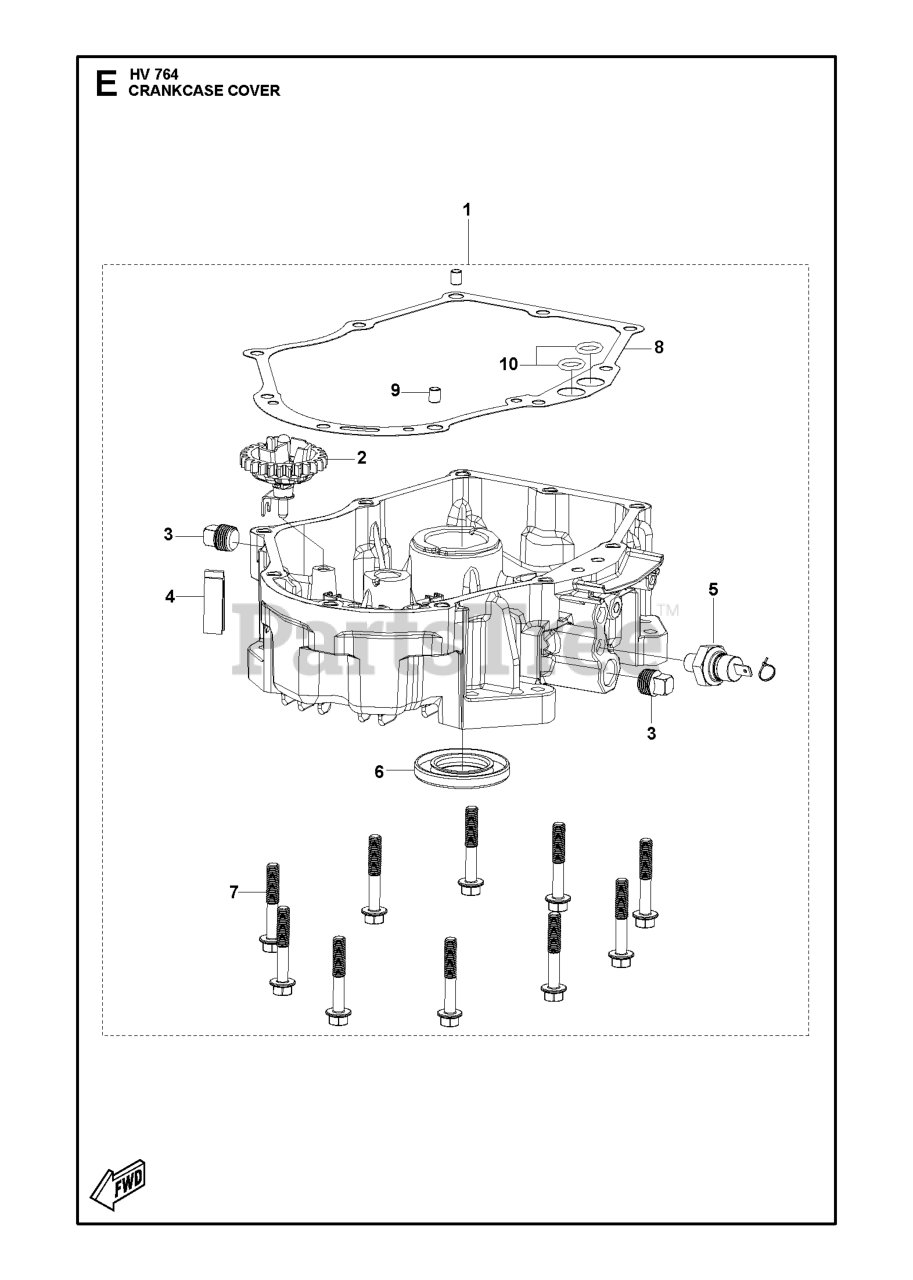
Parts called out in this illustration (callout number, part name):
3	OIL PLUG OIL PLUG
4	BLOCK OIL RETURN BLOCK
9	PIN LOCATION PIN
10	SEALING RING SEAL RING
